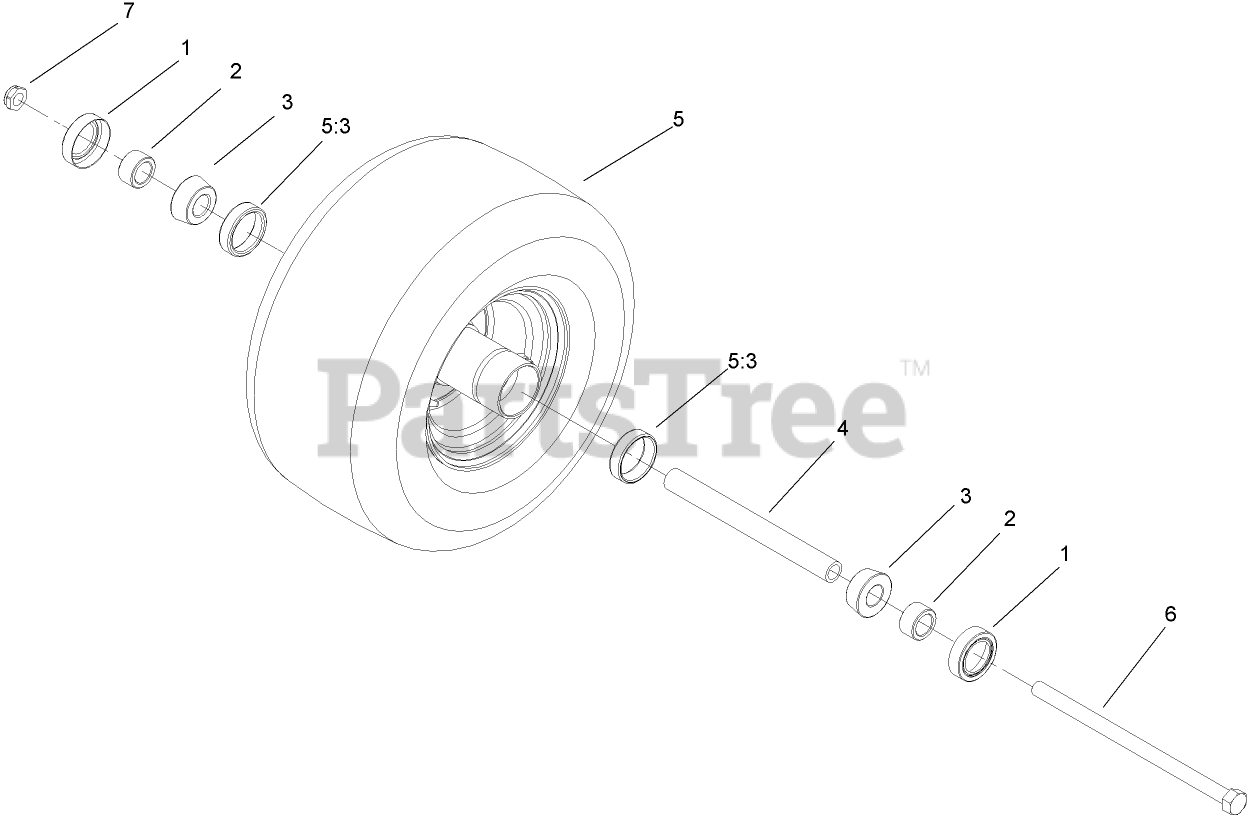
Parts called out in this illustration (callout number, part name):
1	SEAL-BEARING
2	SPACER-BEARING
3	BEARING-CONE, TAPER
4	SPACER-CASTER, FRONT
5	WHEEL AND TIRE ASM (SEMI-PNEUMATIC)
5:3	BEARING-CUP
6	SCREW-HH
7	NUT-LOCK, NI
